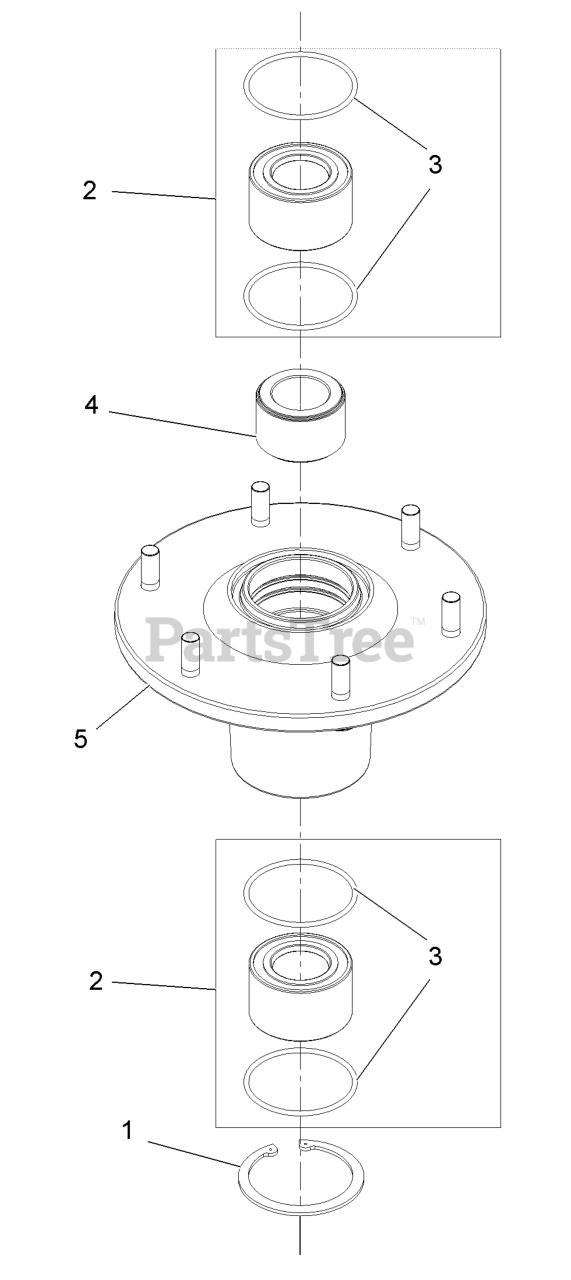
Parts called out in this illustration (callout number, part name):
1	Ring-Retaining
2	Asm, Bearing W/O-Rings
4	Spacer, Bearing
5	Asm, Housing W/Studs
